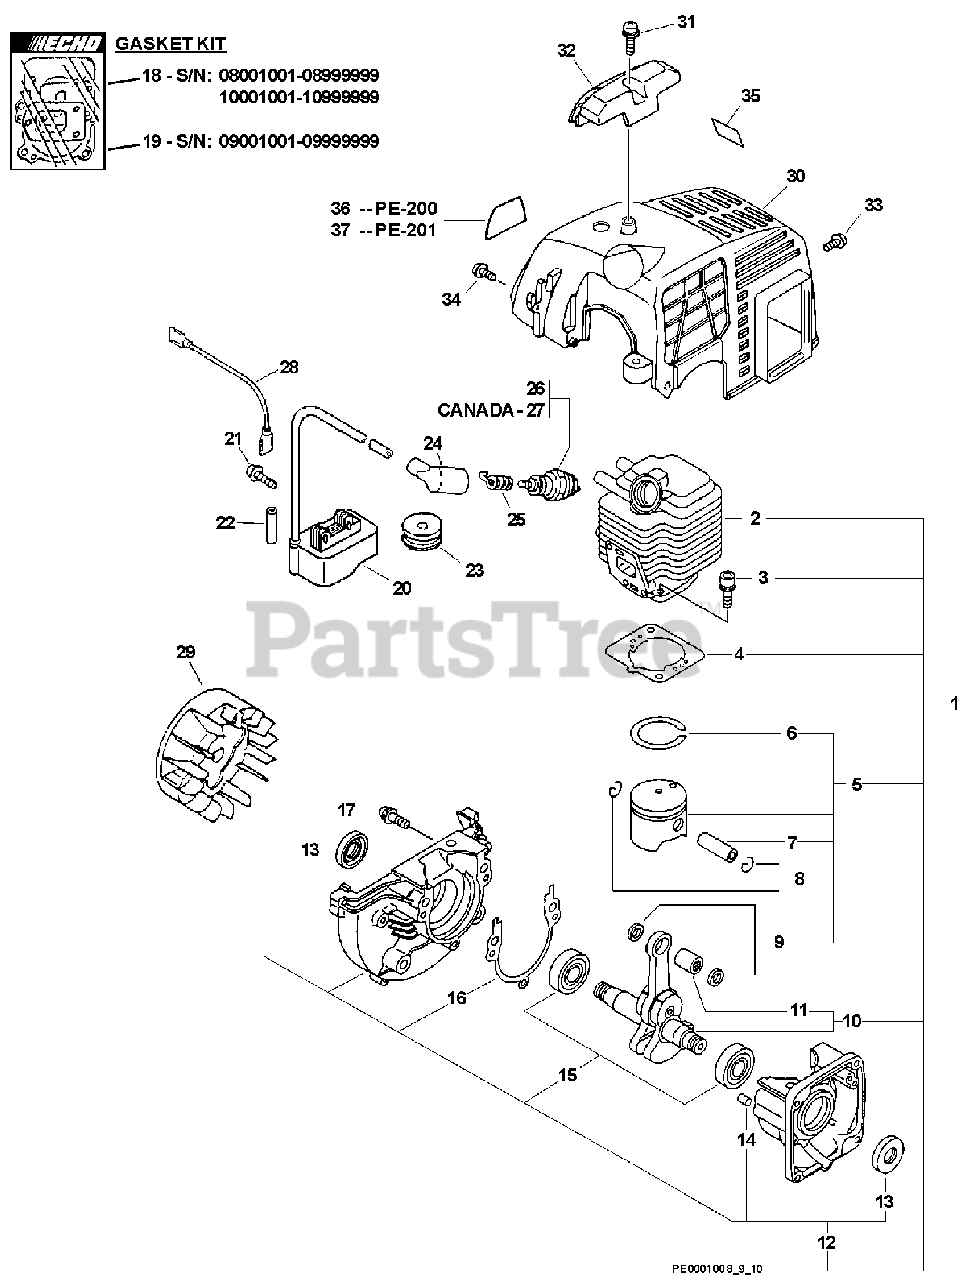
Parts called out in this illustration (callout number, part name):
1	SHORT BLOCK
2	CYLINDER
3	BOLT 5×22
4	GASKET, CYLINDER
5	PISTON KIT
6	RING, PISTON
7	PIN, PISTON 8
8	RING, SNAP
9	WASHER, THRUST
10	CRANKSHAFT ASSY
11	BEARING, NEEDLE 8
12	CRANKCASE KIT
13	SEAL, OIL 12
14	PIN, LOCATING 4
15	BEARING, BALL - 6201 C3
16	GASKET, CRANKCASE
17	BOLT 5×28
18	GASKET KIT
19	GASKET KIT
20	COIL, IGNITION
21	BOLT 4×20
22	TUBE, INSULATOR
24	CAP, SPARK PLUG
25	TERMINAL, SPARK PLUG
26	SPARK PLUG - BPM8Y
27	SPARK PLUG - BPMR8Y
28	LEAD - GROUND
29	FLYWHEEL
30	COVER, ENGINE
31	SCREW 5×16
32	GUARD, TOP
33	BOLT 4×8
34	SCREW 4×12
35	LABEL, CAUTION - HOT
36	LABEL, MODEL
37	LABEL, MODEL
